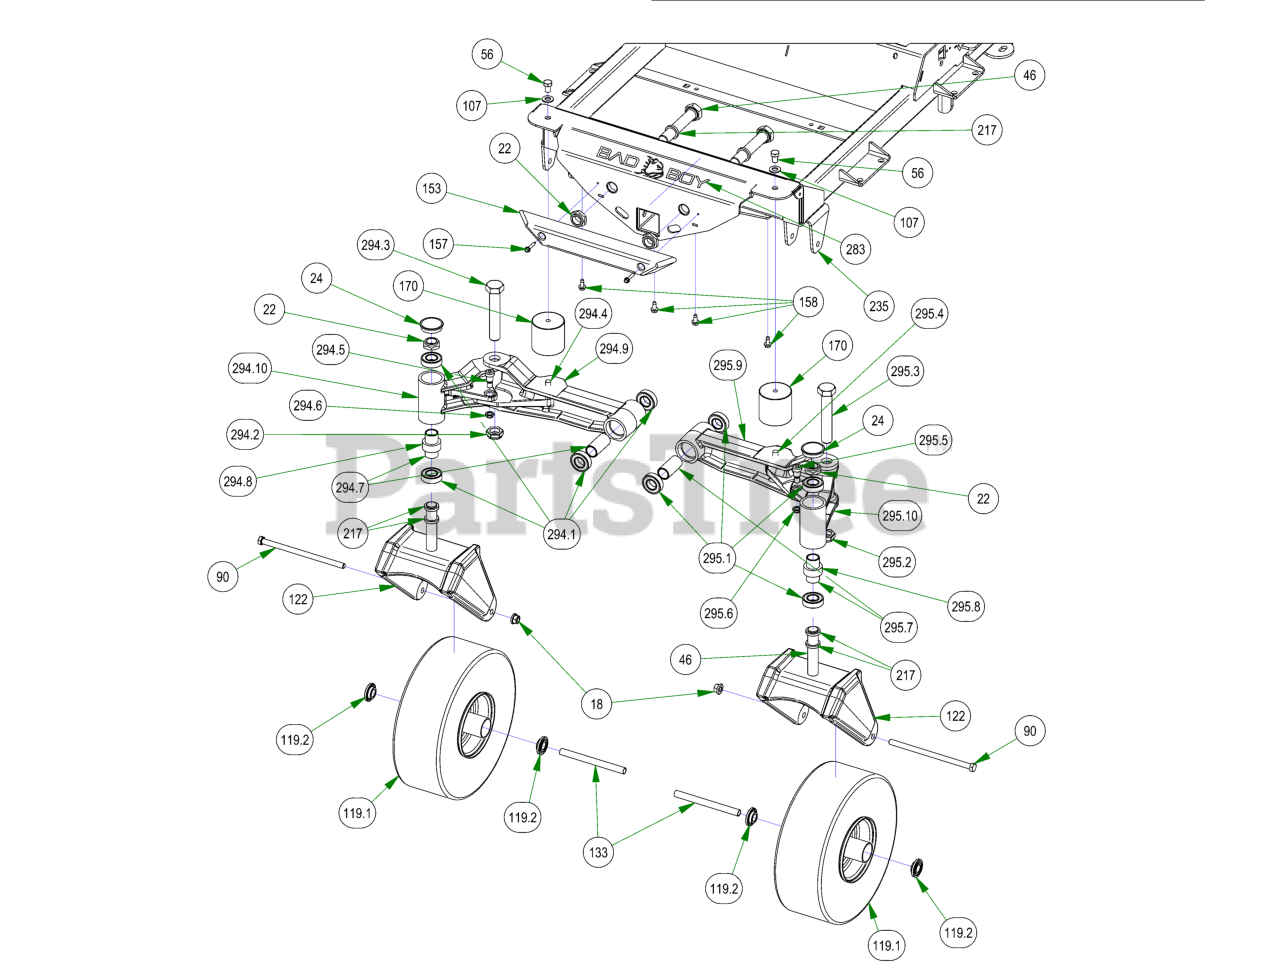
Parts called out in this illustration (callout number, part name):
18	1/2-13 NYLON INSERT FLANGE LOCKNUT ZINC
22	1"-14 NYLON INSERT JAM LOCKNUT ZINC
24	2017 Bearing Cover
46	1"-14 X 5-1/2 HEX CAP SCREW (GR.8) ZINC YELLOW
56	1/2-13 X 3/4 HEX CAP SCREW (GR.5) ZINC
90	1/2-13 X 9 HEX CAP SCREW (GR.5) ZINC
107	1/2 SAE FLAT WASHER (1-1/16" OD) GR.8 ZINC YELLOW
119	2019 15x6.00-6 Non Pneumatic Black Front Assembly
119.2	1-3/4" Bearing-Large Bore Front Rim
122	2020 R Series Cast Front Fork
133	Front Wheel Spanner
153	2017 XP Bumper
157	1/4-14 X 1-1/2 HEX WASHER UNSLOT TEK/3 ZINC
158	5/16-18 X 3/4 HEX WASHER SLOT (F) TCS ZINC
170	Vibration Mount-Blue Dot
217	1.02 ID X 1.38 OD X .250 THK SPACER ZINC
235	2022 Horizontal Diesel Frame
283	Flying Bulldog Front Bumper Decal
286	Independetly Articulating Front Suspension Arms Patent Decal
294	2022 61/72 Rogue/Renegade Front Suspension Asy RH
294.1	1641 BEARING W/2 CONTACT RUBBER SEALS
294.2	1" Fine Thread 1/2 Nylock Nut
294.3	1"-14 X 5-1/2 HEX CAP SCREW (GR.8) ZINC YELLOW
294.4	1/2-13 x 1" Stud
294.5	5/8 X 5/8 SOCKET SHOULDER BOLT ZINC YELLOW
294.6	1/2-13 NYLON INSERT JAM LOCKNUT ZINC
294.7	2016 Front Bearing Spacer
294.8	Rubber Stabilizer (Front Forks) [R series]
294.9	INNER RH FRONT AXLE
294.10	OUTER FRONT ARM RH
295	2022 61/72 Rogue/Renegade Front Suspension Asy LH
295.1	1641 BEARING W/2 CONTACT RUBBER SEALS
295.2	1" Fine Thread 1/2 Nylock Nut
295.3	1"-14 X 5-1/2 HEX CAP SCREW (GR.8) ZINC YELLOW
295.4	1/2-13 x 1" Stud
295.5	5/8 X 5/8 SOCKET SHOULDER BOLT ZINC YELLOW
295.6	1/2-13 NYLON INSERT JAM LOCKNUT ZINC
295.7	2016 Front Bearing Spacer
295.8	Rubber Stabilizer (Front Forks) [R series]
295.9	INNER FRONT ARM LH
295.10	CAST OUTER ARM LH
